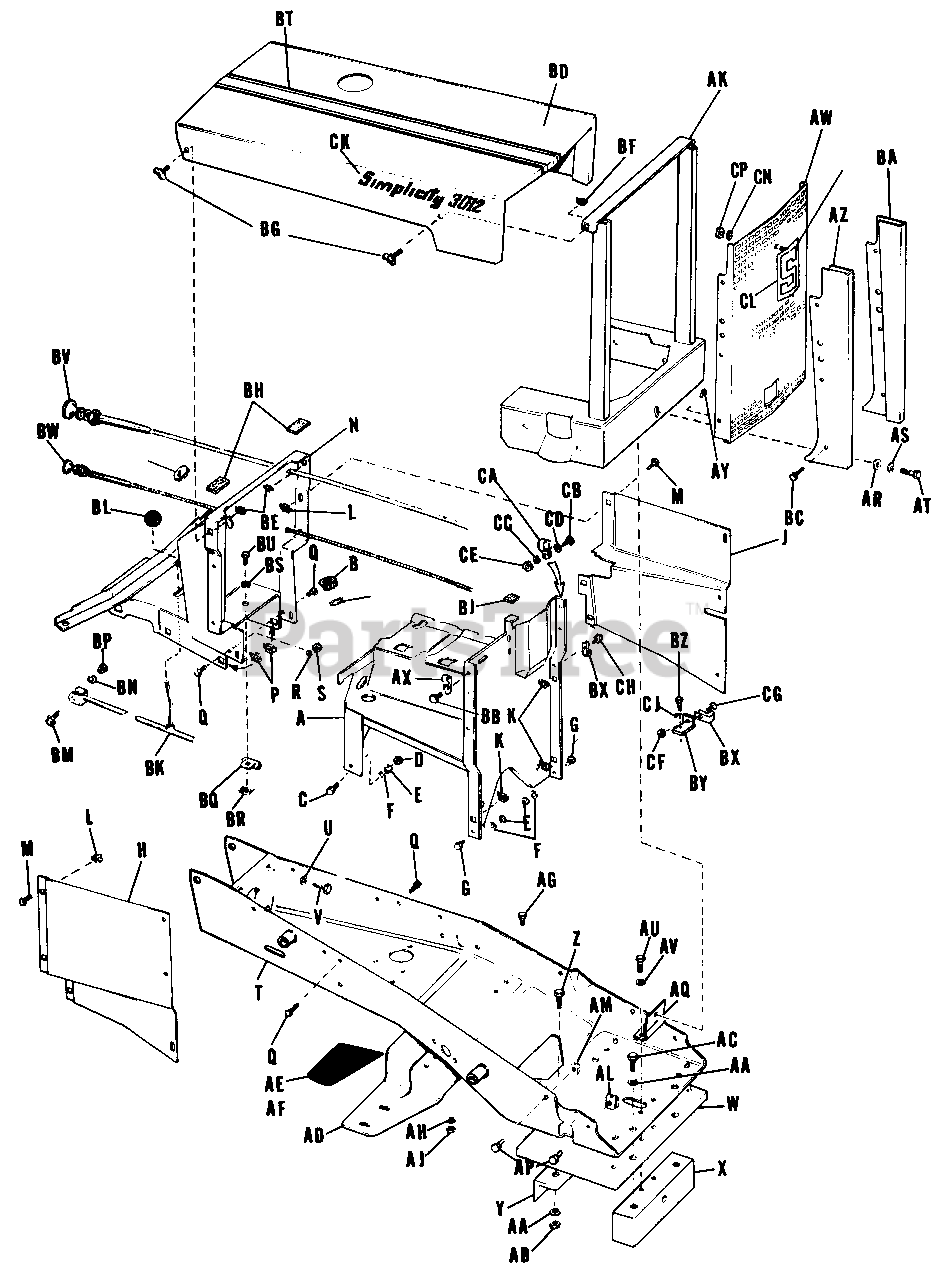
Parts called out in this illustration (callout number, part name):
A	Support Assembly, Fuel Tank & Battery
B	Steering Bushing
C	Hex. Cap Screw, 5/16"-18 x 1-1/4"
D	Full Lock Hex. Nut, 5/16"-18
E	Full Hex. Nut, 5/16"-18
F	Lock Washer, 5/16"
G	Hex. Cap Screw, 5/16"-18 x 5/8"
H	R.H. Side Panel
J	L.H. Side Panel
K	Nut Retainer
L	Nut Retainer
M	Hex. Cap Screw, 1/4"-20 x 5/8"
N	Inst. Panel Assembly
P	Nut Retainer (Frame Cover)
Q	Hex. Cap Screw, 1/4"-20 x 5/8"
R	Lock Washer, 1/4"
S	Full Hex. Nut, 1/4"-20
T	Frame Assembly
U	Lock Washer, 7/16"
V	Hex. Cap Screw, 7/16"-14 x 1-1/2"
W	Base Weight
X	Front Support, 1-3/4" x 2-1/2" x 8-5/8"
Y	Angle Assembly (Frame Rear)
Z	Hex. Cap Screw, 7/16"-14 x 1-1/2"
AA	Lock Washer, 7/16"
AB	Full Hex. Nut, 7/16"-14
AC	Hex. Cap Screw, 7/16"-20 x 1-1/2"
AD	Foot Rest
AE	L.H. Foot Rest Pad
AF	R.H. Foot Rest Pad
AG	Hex. Cap Screw, 3/8"-16 x 3/4"
AH	Lock Washer, 3/8"
AJ	Full Hex. Nut, 3/8"-16
AK	Cover & Tube Assembly
AL	Retainer Nut (Front)
AM	Retainer Nut (Rear)
AP	Hex Screw, Whiz-Lock Flange, 5/16-18 x 3/4
AQ	Bracket Assembly
AR	Plain Washer, 5/16"
AS	Lock Washer, 5/16"
AT	Hex. Cap Screw, 5/16"-18 x 1-1/4"
AU	Lock Washer, 5/16"
AV	Hex. Cap Screw, 5/16"-18 x 1-1/2"
AY	Self Tapping Screw, #810 x 1/2"
AZ	R.H. Side Plate
BA	L.H. Side Plate
BB	Self-Tapping Screw #10-24 x 1/2" lg.
BC	Self Tapping Screw, 10 x 1/2"
BE	Nut Retainer (Rear)
BF	Nut Retainer (Front)
BG	Thumb Screw
BK	Shifter Rod Assembly
BM	Hex. Cap Screw, 5/16"-18 x 1-1/2"
BN	Lock Washer, 5/16"
BP	Full Hex. Nut, 5/16
BQ	Shift Rod Guide Assembly
BR	Retainer Nut
BS	Lock Washer, 1/4"
BT	Hood Strip
BU	Hex. Cap Screw, 1/4"-20 x 5/8"
BV	Throttle Control
BW	Choke Control
BX	Bowden Wire Clip
BY	Throttle Cable Bracket
BZ	Self Tapping Screw, 1/4"-20 x 5/8"
CB	Hex. Cap Screw, 1/4"-20 x 5/8"
CC	Lock Washer, 1/4"
CD	Plain Washer, 1/4"
CE	Full Hex. Nut, 1/4"-20
CF	Full Hex. Nut, #10-32
CG	Mach. Rd. Hd. Screw, #10-32 x 3/8"
CH	Self Tapping Rd. Hd. Screw, #10-24 x 1/2"
CJ	Lock Washer
CK	Simplicity & Number 3012 Film
CL	Plate, ASSAY
CM	Emblem "S"
CN	Washer Lock
CP	Hex Nut #10-24
CQ	Plug Button
CQ	Film, (Front) Sovereign
CQ	Film, Shift Pattern & Safty
CQ	Film, Ignition
CQ	Film, Seat Deck-Rear
CQ	Film, Seat Deck
CQ	Film, Instrument Panel
BN	Film, "Synchro" Balanced
